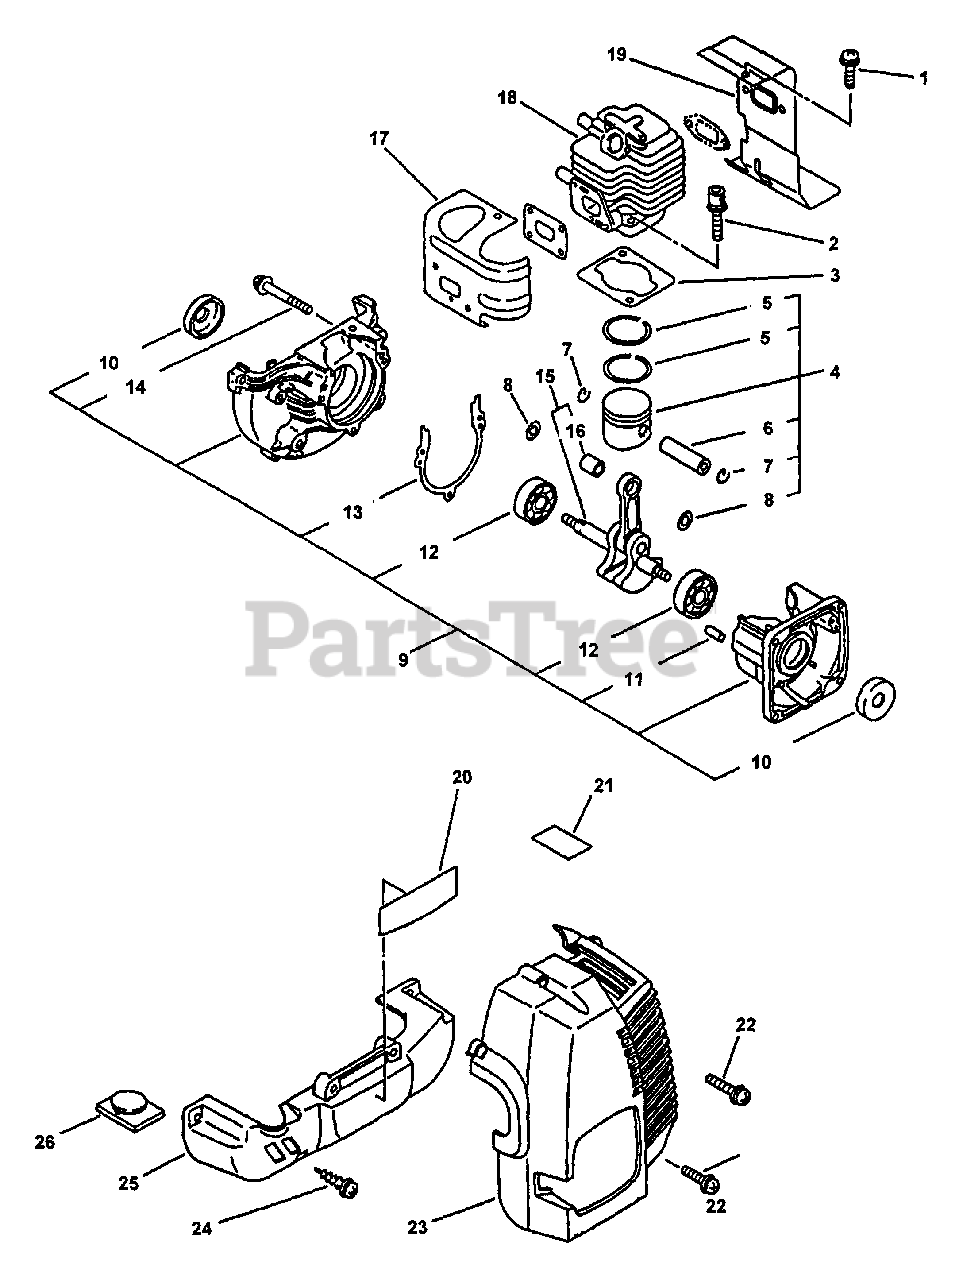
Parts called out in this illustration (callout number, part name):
1	SCREW 5×10
2	BOLT 5×22
3	GASKET, CYLINDER
4	PISTON KIT
5	RING, PISTON
6	PIN, PISTON 8
7	RING, SNAP
8	WASHER, THRUST
9	CRANKCASE KIT
10	SEAL, OIL 12
11	PIN, LOCATING 4
12	BEARING, BALL - 6201 C3
13	GASKET, CRANKCASE
14	SCREW 5×28
15	CRANKSHAFT ASSY
16	BEARING, NEEDLE
17	COVER, CYLINDER
18	CYLINDER
19	COVER, CYLINDER
20	LABEL, MODEL
21	LABEL - CAUTION -- HOT
22	SCREW 5×16
23	COVER, ENGINE
24	SCREW, TAPPING 5×20
25	COVER
